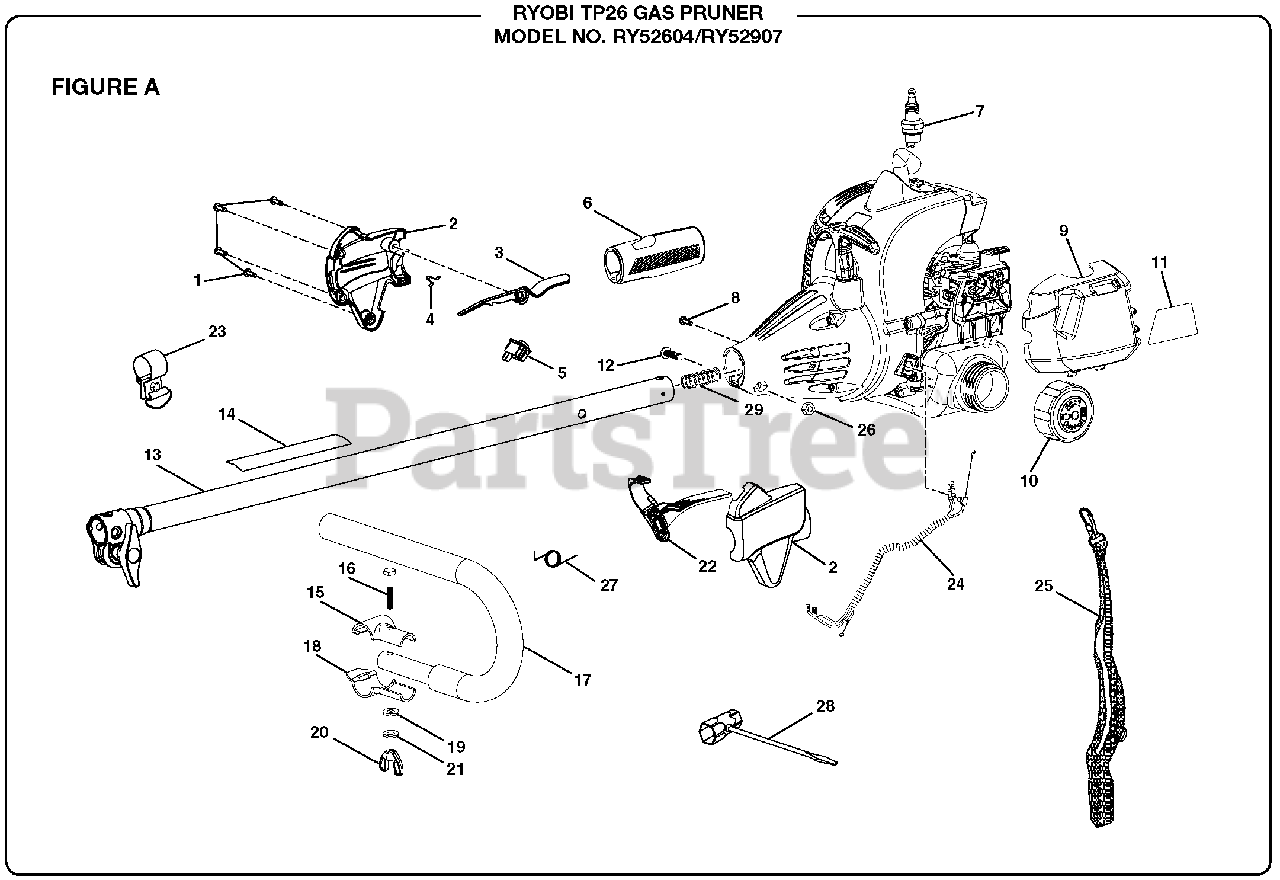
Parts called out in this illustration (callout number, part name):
1	Screw (M4 x 20 mm)
2	Control Handle Assembly
3	Trigger Lock
4	Strap Hanger
5	Switch (Momentary Contact)
6	Rear Handle
7	Spark Plug (Champion RCJ6Y)
8	Screw (8-16 x 5/16 in., Torx T.F.)
9	Air Filter Cover
10	Fuel Cap Assembly (1.5 in. Diameter)
11	Starting Label
12	Bolt (M6 x 20 mm)
13	Upper Boom Assembly
14	Warning Decal
15	Handle Bar Clamp Top "J"
16	Bolt (1/4-20 x 1-1/in., Hex Hd.)
17	"J" Handle w/Grip
18	Handle Bar Clamp Bottom "J"
20	Wing Nut (1/4-20)
21	Lock Washer
22	Throttle Trigger
23	Strap Hanger Assembly
24	Throttle and Lead Assembly (Incl. Key No. 5)
25	Shoulder Harness
26	Hex Nut (M6)
28	Combination Wrench
29	Compression Spring
